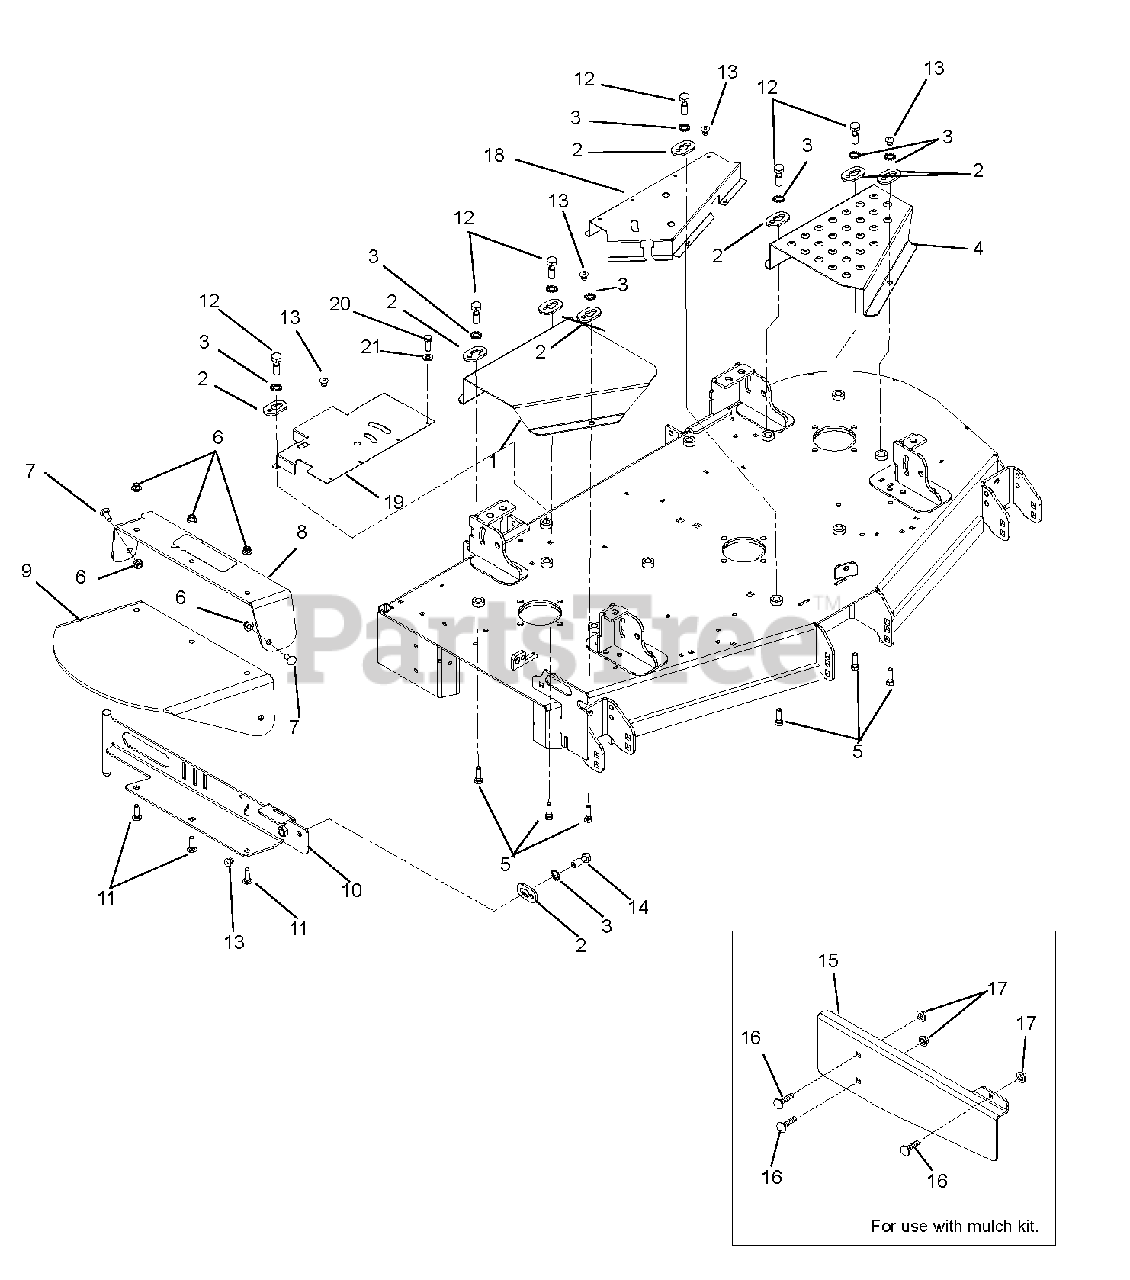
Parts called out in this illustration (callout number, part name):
1	Guard, Right Hand PT200 CE Belt
2	Keeper, Bolt
3	Washer, Locking External .391 x .682 x .036
4	Guard, Left Hand PT200 CE Belt
5	Bolt, Hex .38-16 x 1.25 Grade 5
6	Nut, Locking Nylon Flange .38-16
7	Bolt, Round Head Square Neck .38-16 x 1.00 Grade 5
8	Support, Rubber Discharge Chute
9	Chute, Rubber Discharge
10	Weldment, 52" Discharge Chute Mounting, CE
11	Bolt, Round Head Square Neck .38-16 x 1.25 Grade 5
12	Bolt, Hex .38-16 x 1.25 Grade 5 Captive
13	Rivet, Pip .187 YZ
14	Bolt, Hex .38-16 1.25 Grade 5 Captive
15	Cover, Discharge 52" CE
16	Bolt, Round Head Square Neck .31-18 x 1.00 Grade 5 YZ
17	Nut, Locking Nylon Flange .31-18 YZ
18	Weldment, Front Belt Shield
19	Shield, Belt Rear
20	Bolt, Hex .25-20 x .75 Grade 5 YZ
21	Washer, Flat Steel .231 x .62 x .065 YZ
